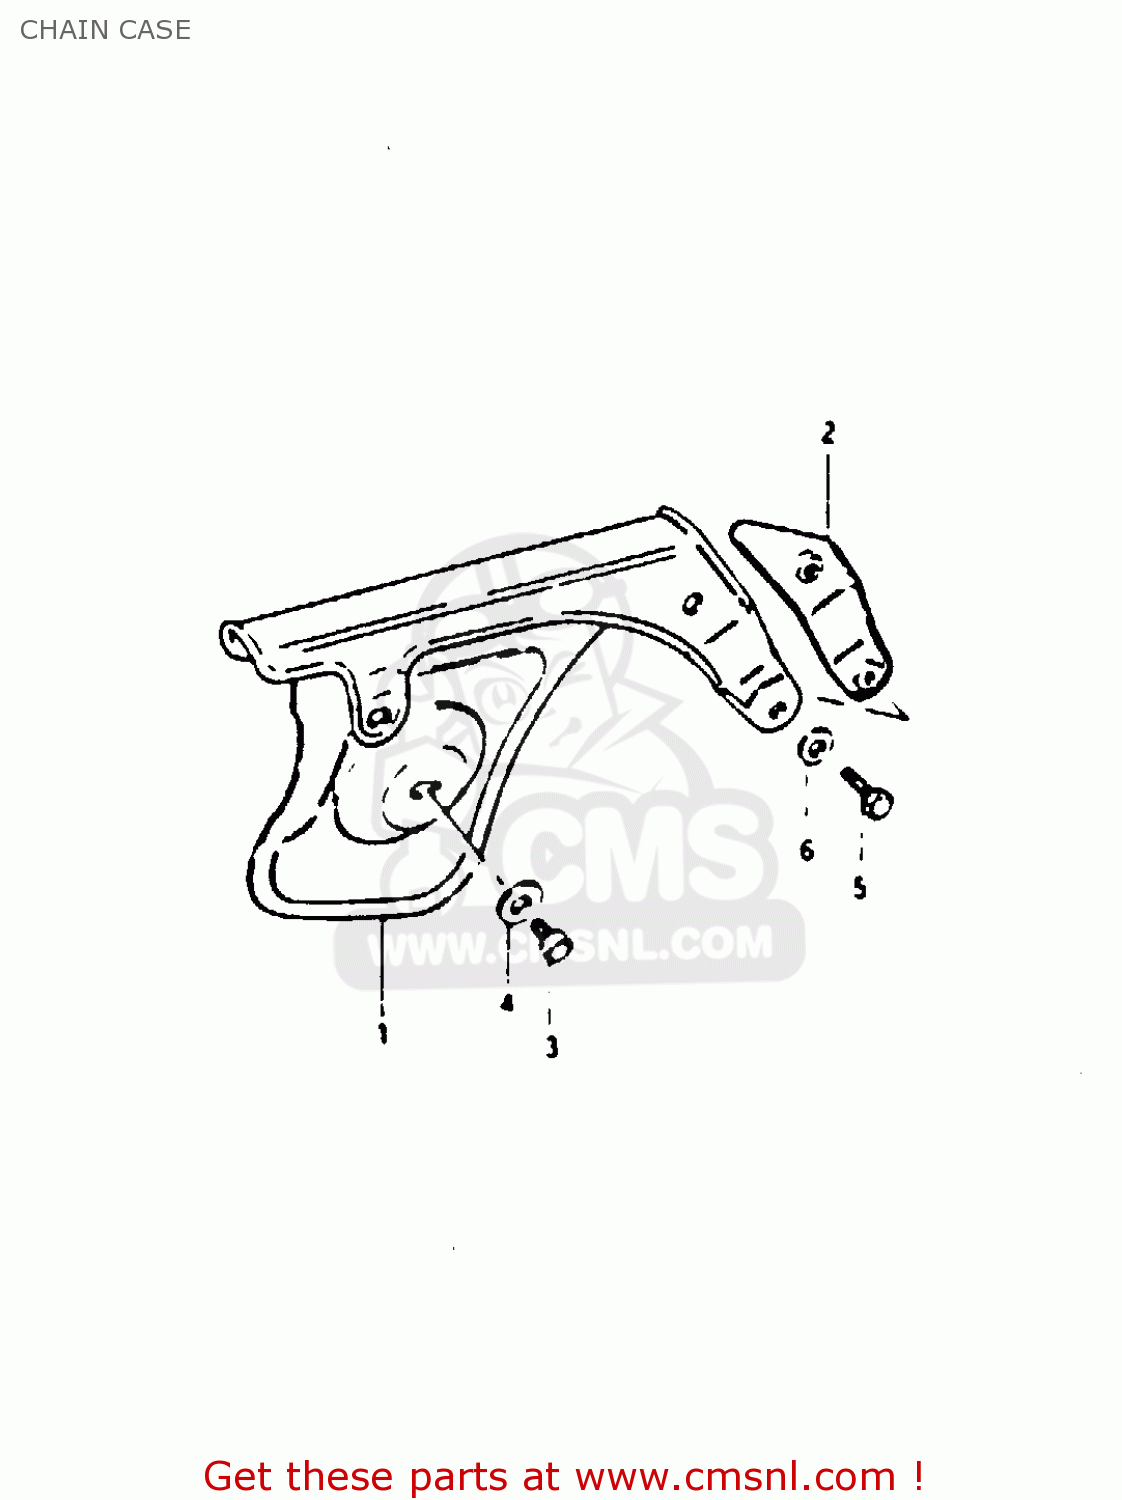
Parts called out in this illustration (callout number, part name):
1	CASE,CHAIN
2	REINFORCEMENT,CHAIN CASE
3	BOLT(6X8)
4	WASHER
5	BOLT, UPPER
6	WASHER
